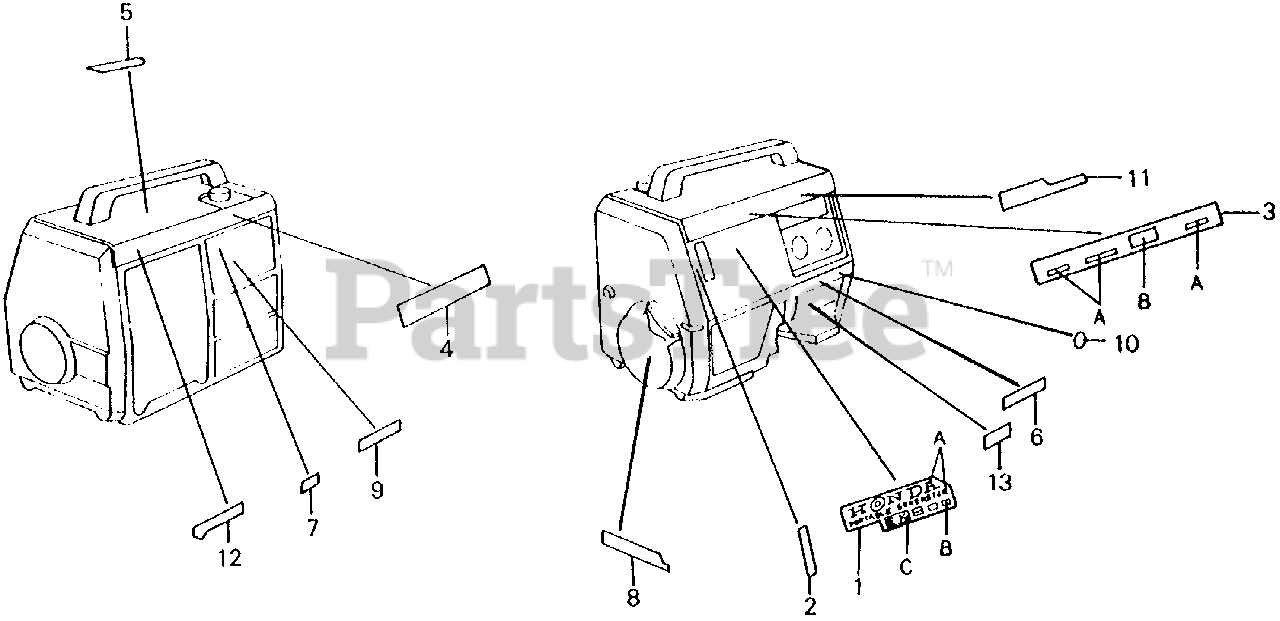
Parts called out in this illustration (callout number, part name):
1	MARK, EMBLEM (TYPE1) (NOT AVAILABLE)
1	MARK, EMBLEM (TYPE2) (NOT AVAILABLE)
2	MARK, ENGINE SWITCH *NH1* (BLACK)
2	MARK, ENGINE SWITCH *NH0* (CHAMPIONSHIP WHITE)
3	MARK, TOP LID *NH1* (BLACK)
3	MARK, TOP LID (TYPE2)
4	PLATE, CAUTION (NOT AVAILABLE)
5	MARK, CAUTION (ENGLISH/FRENCH)(SPANISH)
6	MARK, D.C. OUTPUT *NH0* (CHAMPIONSHIP WHITE)
6	MARK, D.C. CAUTION
7	MARK, CHOKE
8	MARK, HONDA
9	MARK, AIR CLEANER
10	MARK, GROUND
11	MARK, POINTS
12	MARK, EX. CAUTION (ENGLISH/FRENCH)
13	MARK, OIL CAUTION
